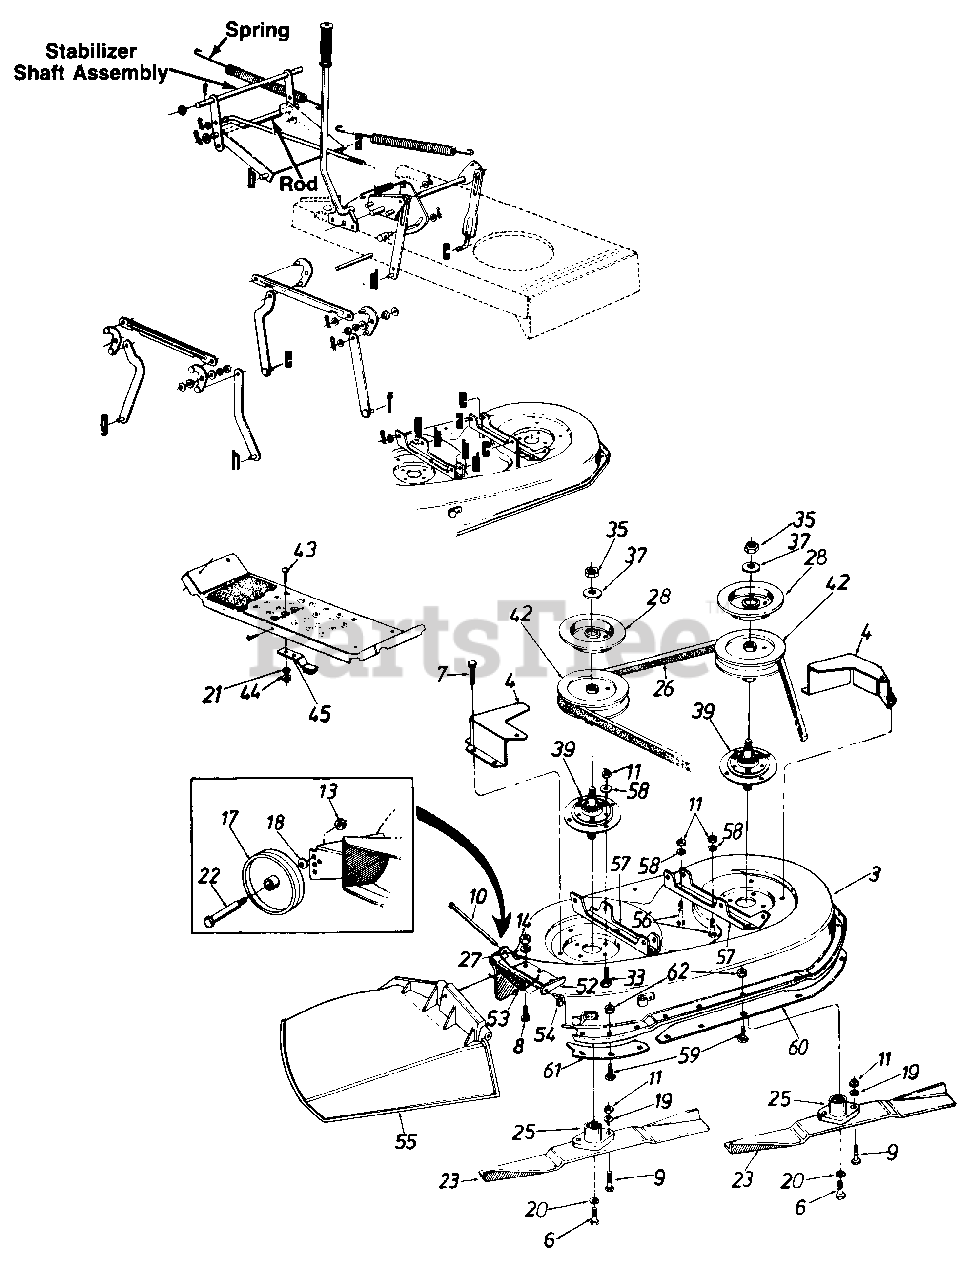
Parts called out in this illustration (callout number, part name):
3	42" Deck Ass'y.
6	Hex Bolt 3/8-24 x 1.0" Lg.
7	Hex Wash. Hd. TT-Tap Scr. 1/4-20 x .5" Lg.
8	Hex Bolt 1/4-20 x .62"
9	Hex Bolt Special 5/16-24 x 1.0"
10	Hinge Pin
11	Hex Nut 5/16-24 Thd.
13	Hex Top L-Nut 3/8-16 Thd.
14	Hex Nut 1/4-20 Thd.
17	Deck Wheel-5"
18	Bell-Wash. .40" I.D. x .88" O.D.
19	L-Wash. 5/16" .D.
20	L-Wash. 3/8" I.D.-H.D.
21	L-Wash. 1/4" I.D.
22	Shld. Bolt .498" Dia. x 1.53"
23	High-Lift Blade
25	Blade Adapter
26	V-Belt
27	Bell-Wash. 1/4" I.D.
28	Brake Disc
33	Hex Bolt 5/16-24 x .75" Lg.
35	Hex Jam Nut 5/8-18 Thd.
37	L-Wash. 5/8" I.D.
39	Blade Spindle Ass'y. Comp.
42	5.5" Dia. Pulley
43	Carr. Bolt 1/4-20 x .62"
44	Hex Nut 1/4-20 Thd.
45	Blade Brake Ass'y.
52	Hinge Mtg. Brkt.
53	Torsion Spring
54	Push Nut
55	Chute Ass'y. Comp.
56	Hex Bolt 5/16-24 x .75" Lg.
59	Carr. Bolt 1/4-20 x .5" Lg.
60	Deck Skirt Ext.-Long
62	Hex Sems Nut 1/4-20 Thd.
